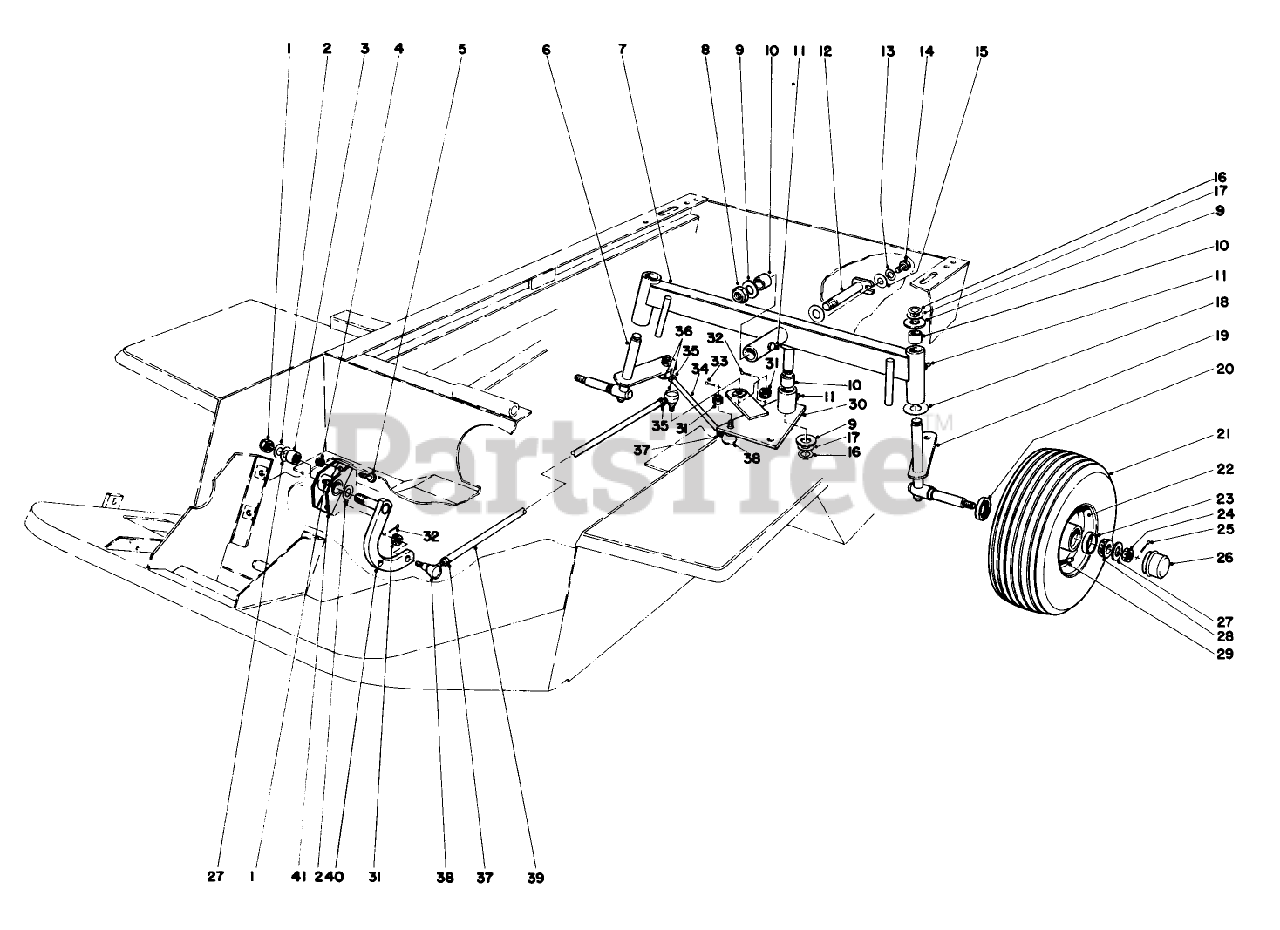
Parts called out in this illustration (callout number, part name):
1	NUT-LOCK, NI
2	THRUST WASHER
3	BEARING-NEEDLE
4	NUT-LOCK, NI
5	SCREW-HH
6	Spindle R.H.
7	Axle (Incl. Ref. #10 & 11)
8	NUT-LOCK, NI
9	WASHER-THRUST
10	BUSHING
11	FITTING-GREASE
12	Pin-RearAxle
13	WASHER-LOCK
14	SCREW-HH
15	WASHER-FLAT
16	RING-RETAINING
17	WASHER
18	WASHER-THRUST
19	Spindle L.H.
21	TIRE 4 PLY
22	Wheel (Incl. Ref. #23)
23	BEARING-CUP, TAPERED
24	NUT-HEX, SLOTTED
25	PIN-COTTER
26	CAP-DUST
27	WASHER-FLAT
28	BEARING-CONE, TAPERED
29	VALVE STEM AND CAP ASM
30	Steering Plate (Incl. Ref. #10 & 11)
31	Jam Nut
32	PIN-COTTER
33	PIN-COTTER
34	Tie Rod Steering
35	NUT-HJ (LH THREAD)
36	Socket Assembly L.H. (Incl. Ref. #31)
37	NUT-JAM
38	Socket Assembly R.H. (Incl. Ref. #31)
39	REAR STRG TUBE PP
40	PIVOT ARM WA
41	Pivot Mount (Incl. Ref. #3 & 11)
